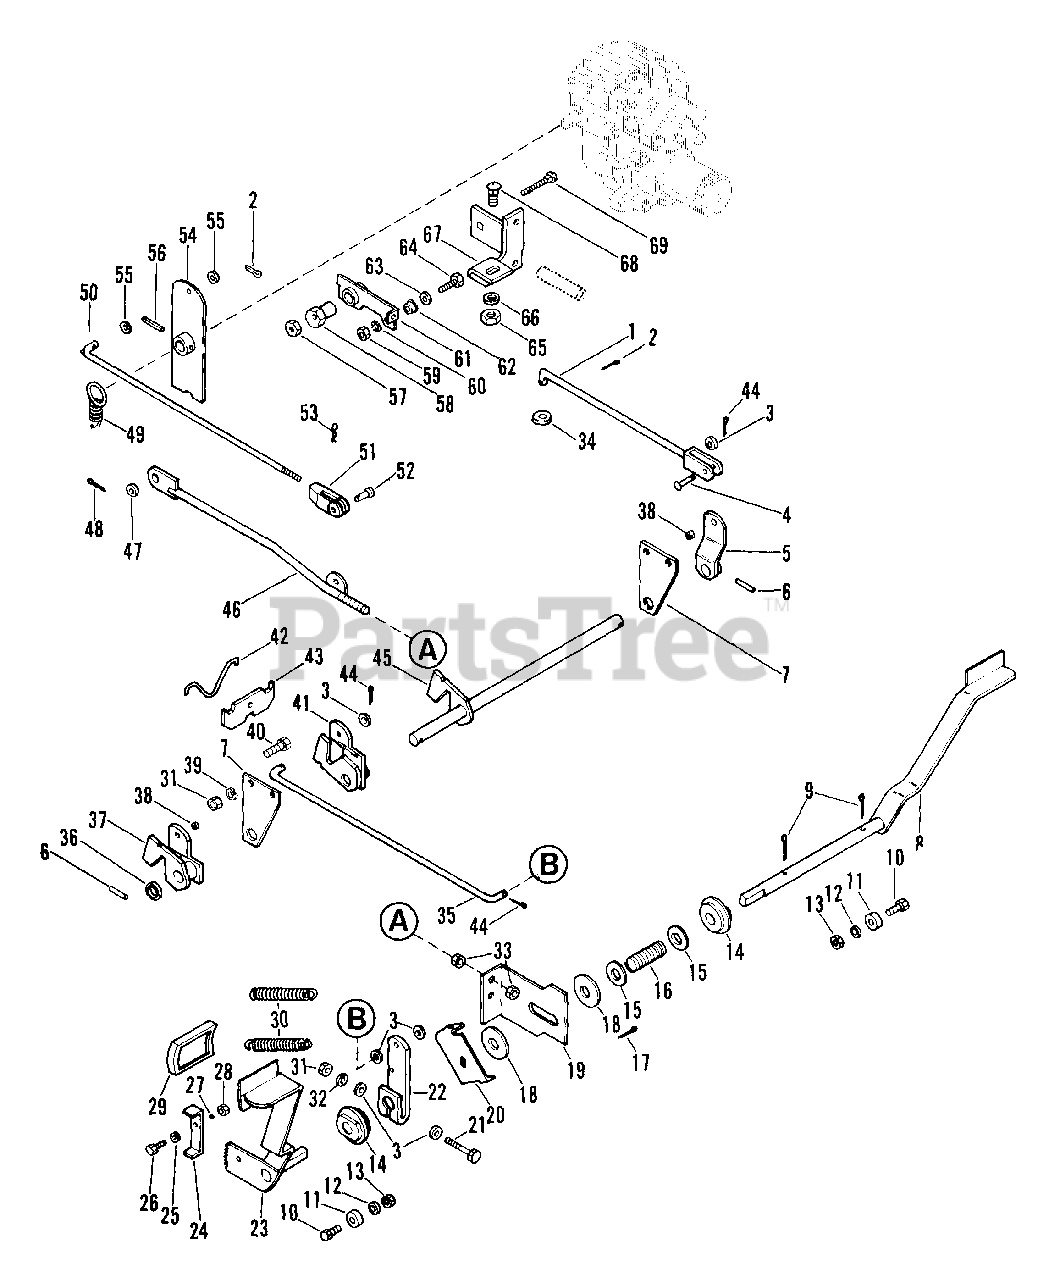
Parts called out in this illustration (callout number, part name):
1	BRAKE ROD
2	PIN-COTR .09X.75 PL
3	WSHR-FL-STL.406X.812X.065PL
4	PIN-CLEV .373X1.12 YWZC
5	BRAKE ARM
6	PIN-GRV .250X1.25 TP A
8	L. H. LEVER
9	PIN-COTR .18X1.25 PL
10	BLT-HEX .31-18X.88 PL GR2
11	SPACER .344X1.000X.375
12	WSHR-FL-STL .38X.875X.083 PL
13	NUT-LK .312-18 GR A PL
14	BSHG-FLG .750X1.750X.875X2.125
15	WSHR-FL-STL .755X1.375X.062 PL
16	SG-COMP .148X1.23X2.53 WLD87
17	PIN-COTR .09X1.0 PL
18	WSHR-FL-STL .755X2.000X.125
19	NEUTRALIZER PLATE
20	NEUTRALIZER ARM
21	BLT-HEX .38-16X2.25 GR2
22	ARM-BRAKE
23	R. H. LEVER
24	BRAKE LATCH
25	WSHR-FL-STL.281X.62X.065 PL
26	BLT-HEX .25-20X.75 PL GR2
27	SPACER BUSHING .37 X .26 X .14
28	NUT-LK-CTR .250-20 PL
29	PEDAL PAD
30	SG-TENS .090X.75X3.50 WLD 34
31	NUT-HEX .375-16
32	WSHR-LK .375X.094 MED PL
33	NUT-LK-CTR .50-13
34	WSHR-FL-STL .382X.812X.023 PL
35	BRAKE ROD
36	WSHR-FL-STL .754X1.125X.062 PL
37	BRAKE ARM
38	GROMMET
39	WSHR-LK .375X.115 HVY PL
40	BLT-RDHDSQSHNK .38-16X1.00 PL
43	BALANCE LINK
44	PIN-COTR .12X.75 PL
45	BRAKE SHAFT
46	NEUTRALIZER ROD
47	WSHR-FL-STL .531X1.062X.095 PL
48	PIN-COTR .12X1.0 PL
49	SG-TENS .080X.75X2.81 WLD 20
50	SHIFT ROD
51	YOKE
52	CLEVIS PIN
53	PIN-HAIR INT .08X.18X1.18
54	SHIFT ARM
55	WSHR-FL-STL .323X.625X.062 PL
56	PIN-ROLL .250X1.38
57	NUT-LK-NYL.312-18 PL
58	ECCENTRIC
59	NUT-LK-CTR .250-20 PL
60	WSHR-LK .250X.047 LT PL
61	DETENT ARM
62	BRG BALL DBL .250X.638X.438
63	WSHR-FL-STL .281X1.250X.048PL
64	BLT-HEX .25-20X1.00 GR2
65	NUT-LK-CROWN .50-13 GR C PL
66	WSHR-FL-STL .531X1.062X.095 PL
67	MOUNT WELDMENT
68	BLT-RDHDSQNK .50-13X1.25GR5PL
69	BLT-RDHDSQNK.31-18X2.25 PL
